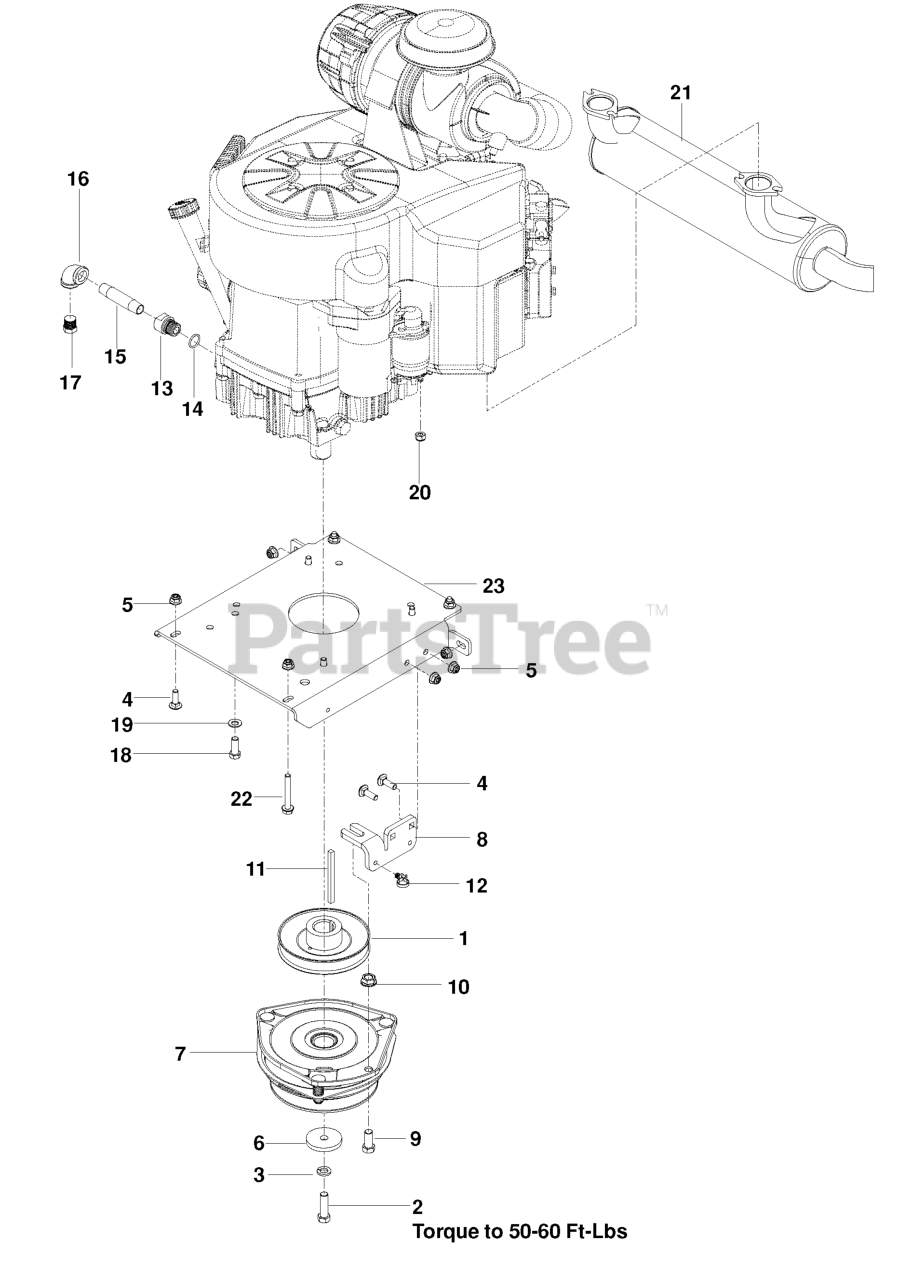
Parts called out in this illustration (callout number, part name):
1	PULLEY, ENGINE
2	HCS 7/16F X 1 1/2
3	WASHER 7/16 LOCK
4	RHSNB 5/16C X 1
5	5/16-18 NYLOC FLANGE NUT
6	BLADE WASHER
7	CLUTCH, GT3.5
8	STOP, CLUTCH, OGURA
9	HCS 7/16-14 X 1 GR 5 ZD
10	NUT 7/16C WHIZ
11	KEY, 1/4 SQ X 3.5
12	TIE WRAP, 8-3/8", W/CLIP
13	ADAPTER, OIL DRAIN
15	PIPE NIPPLE 3/8 X 3
16	90 DEG.ELBOW 3/8NPT
17	PLUG, DRAIN 3/8 NPTF
18	HCS 3/8-16X1.GRD.5.ZD
19	WASHER, 3/8 DISC SPRING SPEC
20	NUT M8-1.25 TOP NYL GR10 ZD
21	MUFFLER, 29HP KAW FX751V-850V
22	HHFS 5/16-18 X 2.25 GD 5
23	PLATE.ENGINE.BLACK
